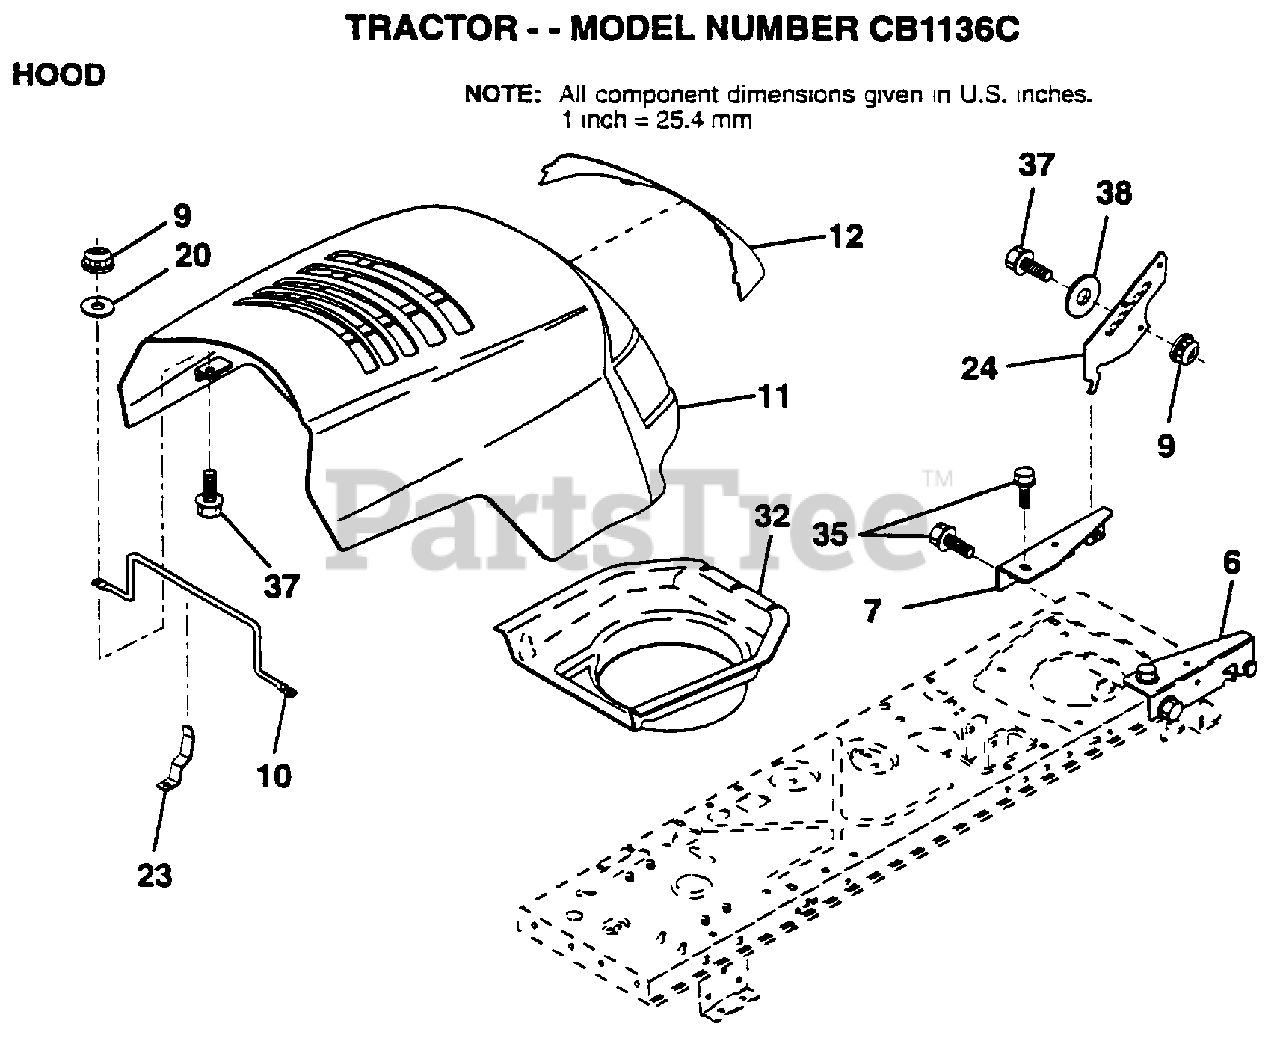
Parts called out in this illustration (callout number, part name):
6	BRACKET ASM HD RH
7	BRACKET ASM HD LH
9	NUT
10	ROD SUPT HOOD
11	HOOD/GRILLE.505
12	LENS.PL.BAR.CLEAR
20	WASHER
23	LATCH.HOOD.LR
24	BRACKET.PVT.HOOD
32	DUCT.INTAKE.AIR
35	SCREW
37	BOLT LT
38	WASHER
